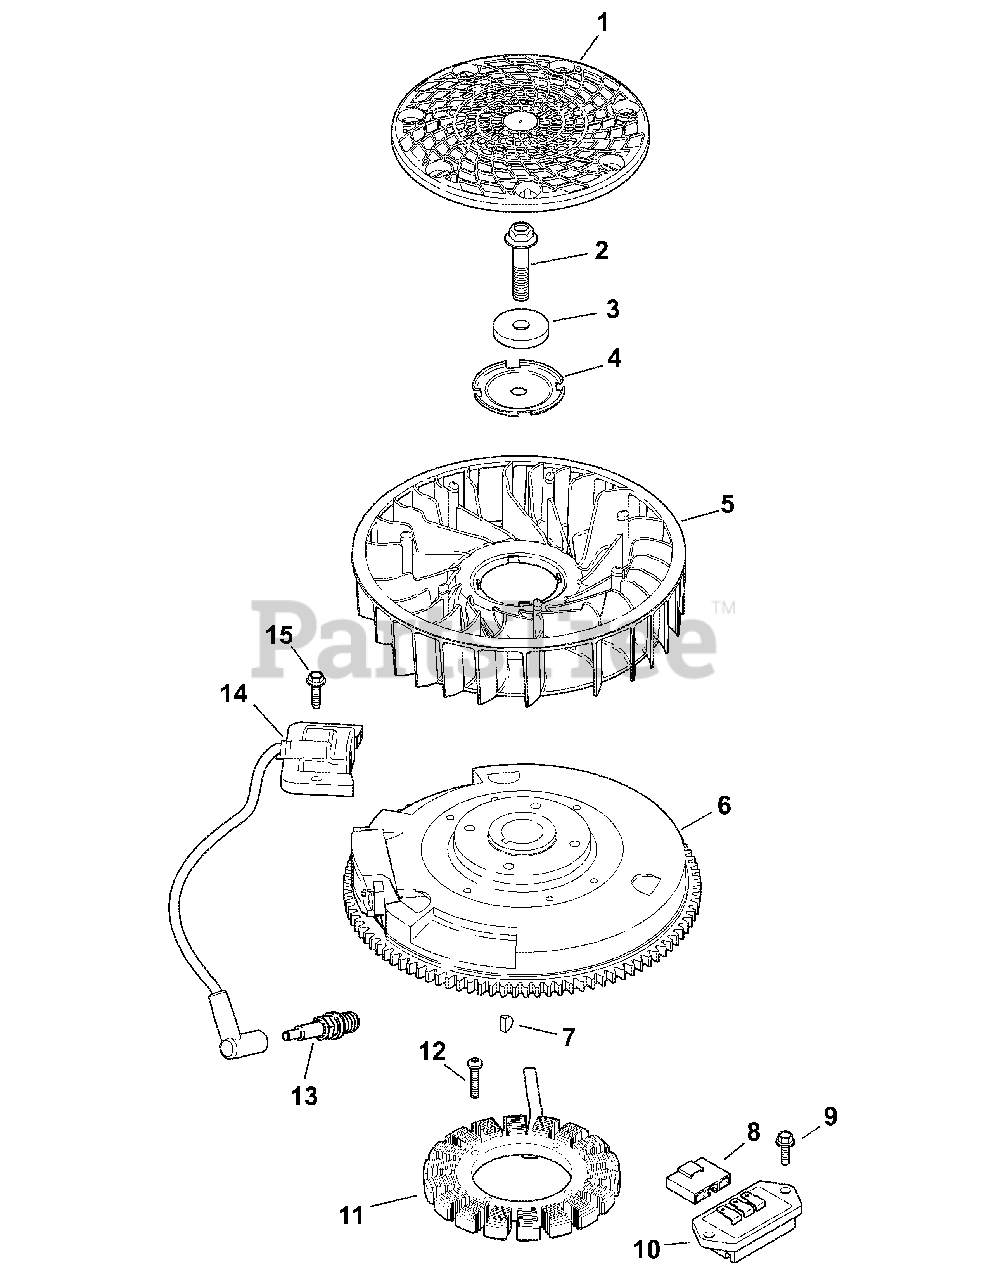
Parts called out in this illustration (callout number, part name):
1	Screen, Grass
2	Screw, FLG M10X1.5X45
3	Washer, Flat 13/32"
4	Plate, Fan Mounting
5	Fan
6	Flywheel
7	Key, 3/16" x 5/8"
8	Connector (3 Contact)
9	Screw, Hvy Flg M5 x 0.8 x 16
10	Rectifier-Regulator
11	Kit, 15 Amp Stator
12	Screw, TRX HD Drive Fastener
14	Module, Ignition (CDI Fixed)
15	Screw, FLG THD FRM M5 x 0.8 x 20
